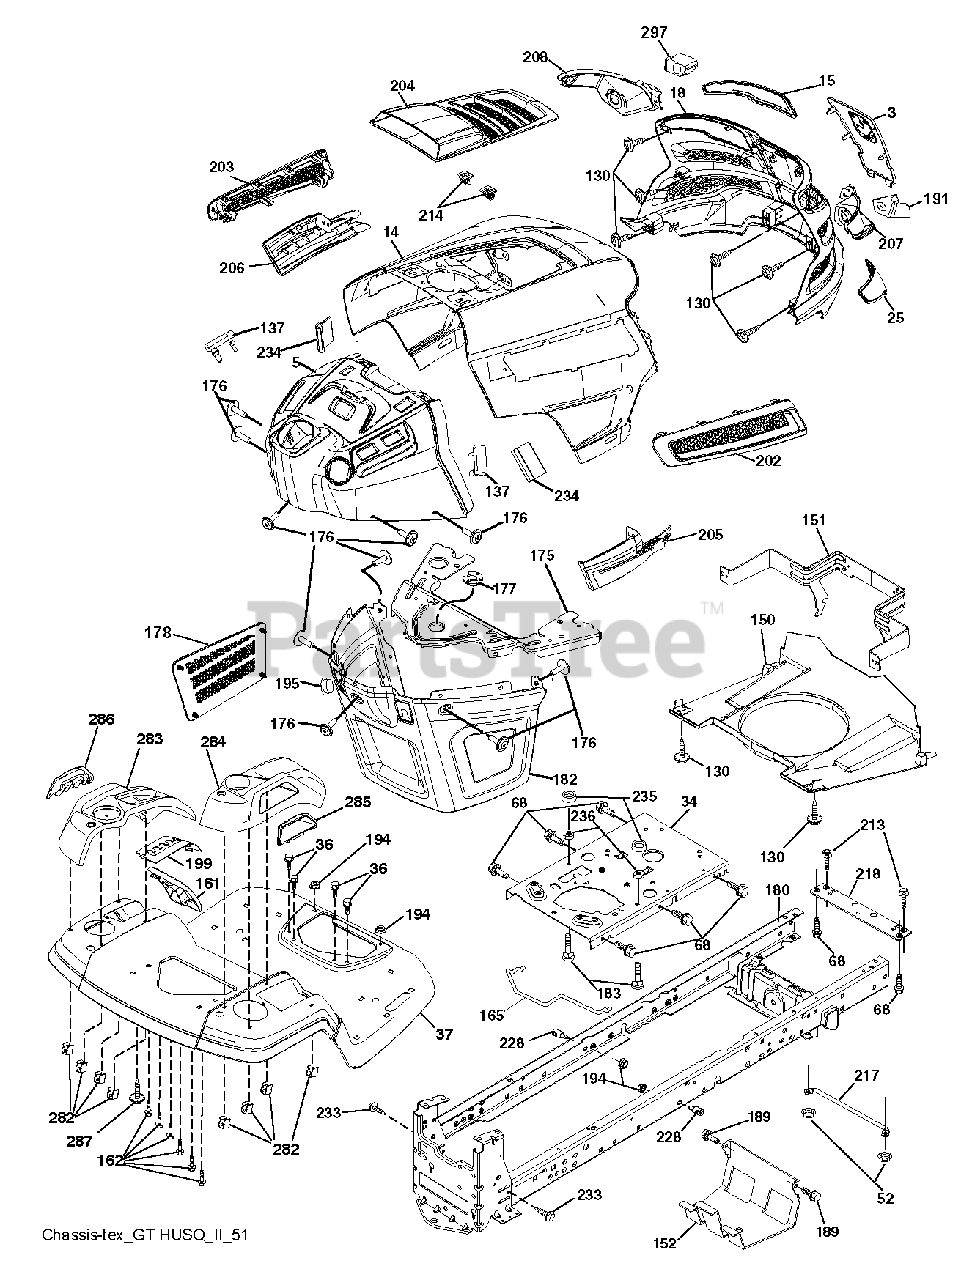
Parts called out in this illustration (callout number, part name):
3	APPLIQUE.SUBASM.GT.HUSQ.II
5	DASH.UPP.GT2.SM.PTO.MCHOKE
14	HOOD.ASM.HUSQVARNA.GT.TEX.ORAN
15	LENS.HEADLIGHT.LH.GTII.2011
18	GRILLE.SUBASM.GT.HUSQ.II
25	LENS.HEADLIGHT.RH.GTII.2011
34	PLATE.ENGINE.WELDED.CHASSIS
36	SCREW 5/16"
37	FENDER.TLT.FS.W/CPH/FW/RSF.668
52	LOCKNUT
68	SCREW LT
130	SCREW.#10 X 0.750.BOS
137	BUMPER DASH
150	AIR.DUCT.GTV.BLACK
151	BRACKET.PIVOT.HOOD.GT.HUSQ.II
152	SHIELD.BROWNING.W/TEX
161	WINDOW.FUEL.LT.HUSQ.TEX.498
162	SCREW.HI-LO.CONSOLE
165	SUPPORT.TANK.REAR.W/TEX
175	PLATE.CROSSMEMBER.HUSQ
176	SCREW.#10-24X5/8.RN.QU
177	BUSHING, STEERING
178	CARGO.ASM.NET.TXGT.W/C
180	CHASSIS
182	DASH.LOWER.COMMON.12V.ADAPTOR
183	BOLT.5/16-18X1-1/4 FULL THD
189	SCREW
191	INSERT.REFLECTIVE.RH.HUSQ.GTII
194	NUT LOCK HEX FLANGE 5/16-18
195	PLUG.HOLE.DASH.LOWER.12V.BLK
199	PLATE.DECK.LIFT.HUSQ.LT
202	VENT.SIDE.RH.GT.HUSQ.II.
203	VENT.SIDE.LH.GT.HUSQ.II.498
204	VENT.TOP.HUSQ.GT2
205	SIDE.TRIM.RH.GT.HUSQ.II
206	SIDE.TRIM.LH.GT.HUSQ.II.GRAY
207	BEZEL LIGHT.RH.GT.II.MYLAR
208	BEZEL LIGHT.LH.GT.II.MYLAR
213	BOLT
214	CLIP.RETAINER.TINNER.
217	ROD.PIVOT.HOOD
218	X-PIECE.HOOD.STOP.NON/
228	STUD.FASTNER.W/ANTI-ROTATE
233	BOLT.SHOULDER
234	BUMPER.HOOD.TEX.HUSQVARNA
235	SPACER FENDER
236	NUT.CENTERLOCK.5/16-
282	CLIP.RETAINER.CONSOLE.LT.HUSQ
283	CONSOLE.DECK.LIFT.R.SDFL.HUSQ
284	CONCOLE.CNTRL.PDL.HUSQ.LT.498
285	CONSOLE INSERT RH
286	CONSOLE.INSRT.LH.HUSQ.LT.BLACK
287	SCREW 1/4X20
297	INSERT.REFLECTIVE.LH.HUSQ.GTII
